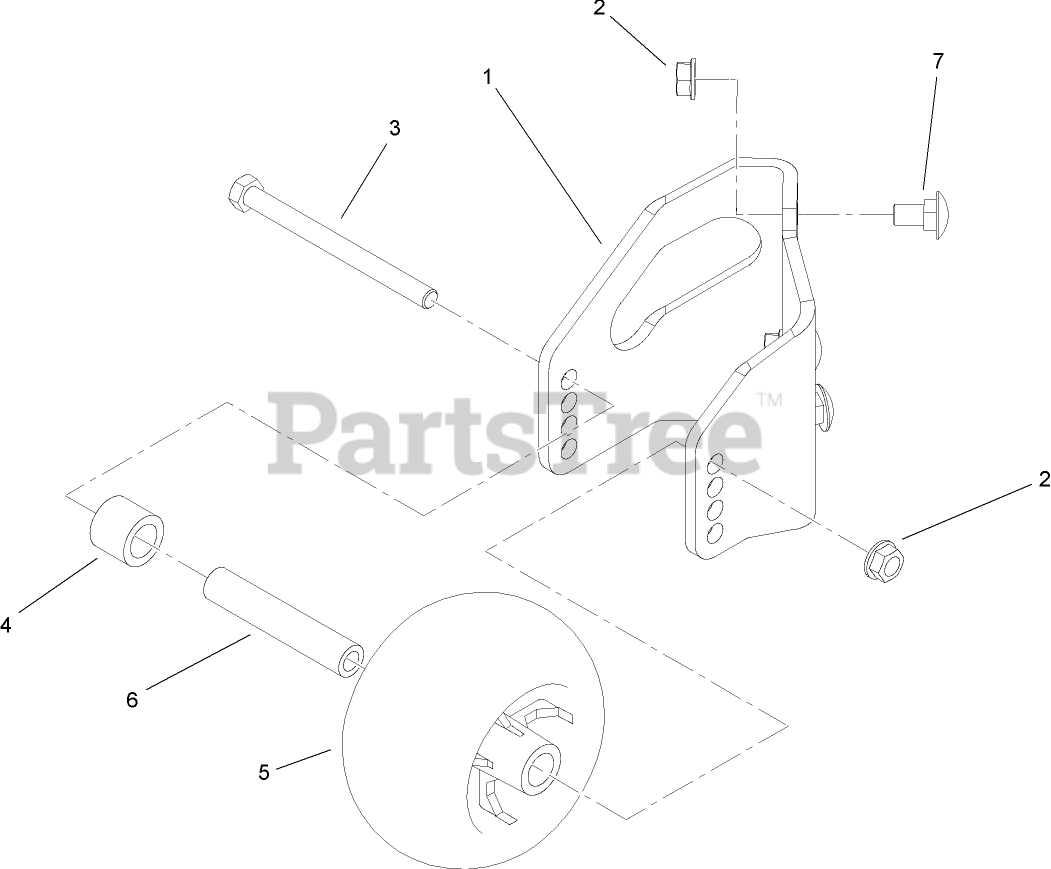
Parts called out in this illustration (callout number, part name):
1	MOUNT-WHEEL, LH
2	NUT-HHF, WHIZ
3	SCREW-HH
4	TUBE-SPACER
5	ROLLER-SCALP, ANTI
6	TUBE-SPANNER
7	SCREW-CARR
